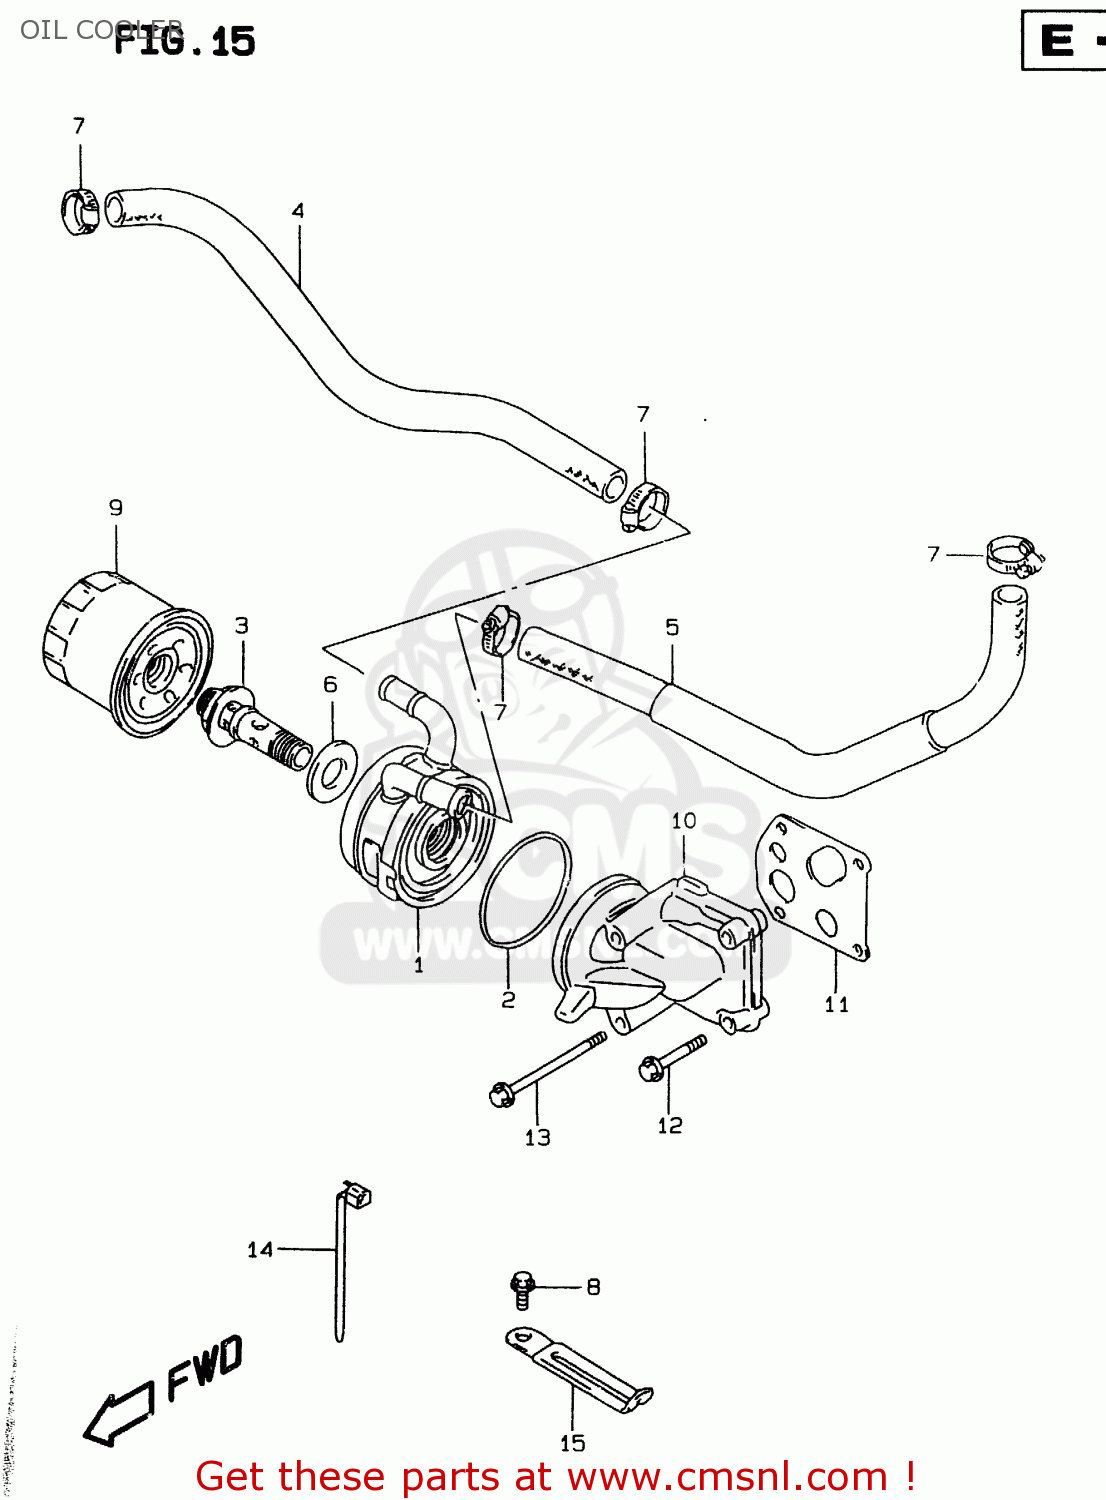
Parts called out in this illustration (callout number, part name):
1	COOLER ASSEMBLY,OIL
2	O RING(D:3.1,ID:63.9)
3	BOLT,OIL COOLER UNION
4	HOSE,OIL COOLER WATER IN
5	HOSE,OIL COOLER WATER OUT
6	SHIM
7	CLAMP
8	BOLT 6X12
9	FILTER ASSEMBLY,ENGINE OIL
10	HOLDER,OIL FILTER
11	GASKET,OIL FILTER HOLDER
12	BOLT(6X40)
13	BOLT(6X65)
14	CLAMP(L:235)
15	CLAMP(L:80)
